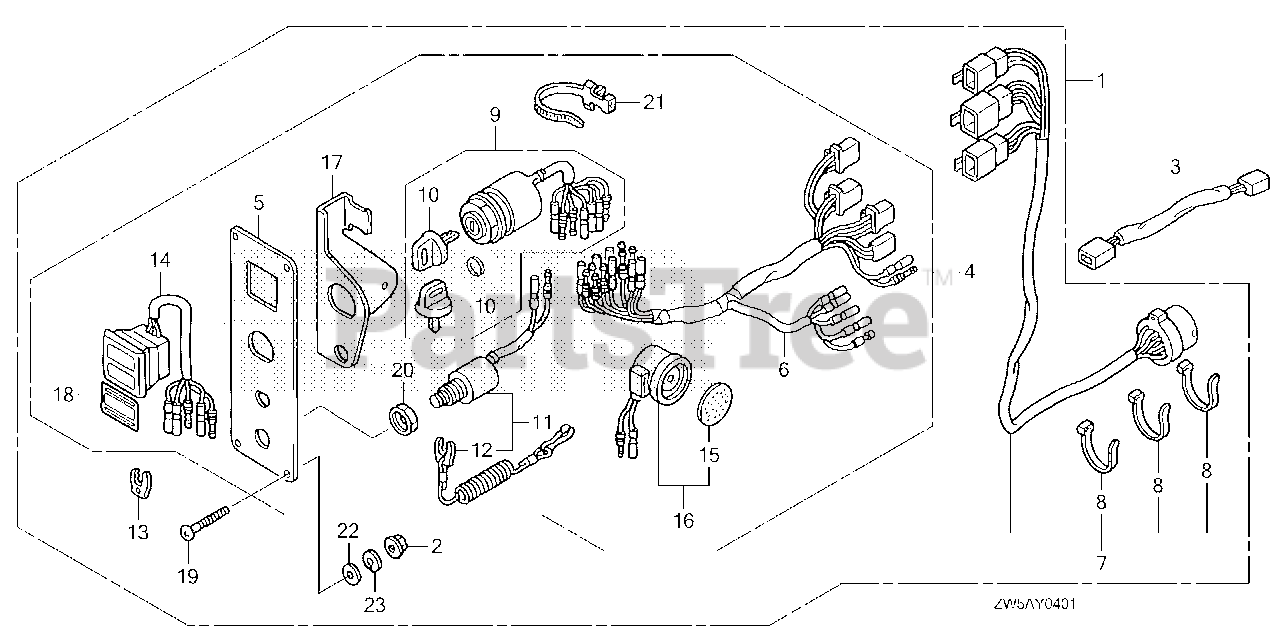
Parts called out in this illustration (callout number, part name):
1	PANEL KIT, SWITCH (SINGLE)
1	PANEL KIT, SWITCH (DUAL)
2	NUT, FLANGE (5MM) DUAL QTY = (8) (SINGLE)
3	HARNESS ASSY., POWER TRIM-TILT DUAL QTY = (2) (SINGLE)
4	PANEL ASSY., CONTROL (2-LED)
5	PANEL, CONTROL
6	HARNESS ASSY., SWITCH PANEL DUAL QTY = (2) (SINGLE)
7	CABLE ASSY., SWITCH PANEL
8	TIE, CABLE (2.4X92) (NATURAL) DUAL QTY = (6) (SINGLE)
9	SWITCH ASSY., COMBINATION DUAL QTY = (2) (SINGLE)
9	SWITCH ASSY., COMBINATION (SINGLE) (DUAL)
10	KEY ASSY., COMBINATION SWITCH (35100-ZV5-003 ONLY) DUAL QTY = (4) (SINGLE)
11	SWITCH ASSY., EMERGENCY STOP (SINGLE) (DUAL)
11	SWITCH ASSY., EMERGENCY STOP
12	WIRE, EMERGENCY DUAL QTY = (2) (SINGLE)
12	WIRE, EMERGENCY (SINGLE) (DUAL)
13	CLIP, EMERGENCY LOCK (SINGLE) (DUAL)
14	LAMP ASSY., INDICATION (2-LED) DUAL QTY = (2) (SINGLE)
15	PLATE, TURN SIGNAL BUZZER DUAL QTY = (2) (SINGLE)
16	BUZZER, WARNING DUAL QTY = (2) (SINGLE)
17	BRACKET, BUZZER DUAL QTY = (2) (SINGLE)
18	MARK, SWITCH PANEL DUAL QTY = (2) (SINGLE)
19	SCREW, PAN (5X40) DUAL QTY = (8) (SINGLE)
20	NUT, HEX. (16MM) DUAL QTY = (2) (SINGLE)
21	BAND, WIRE HARNESS (150MM) (NATURAL) DUAL QTY = (2) (SINGLE)
22	WASHER, PLAIN (5MM) DUAL QTY = (8) (SINGLE)
23	WASHER, SPRING (5MM) DUAL QTY = (8) (SINGLE)
